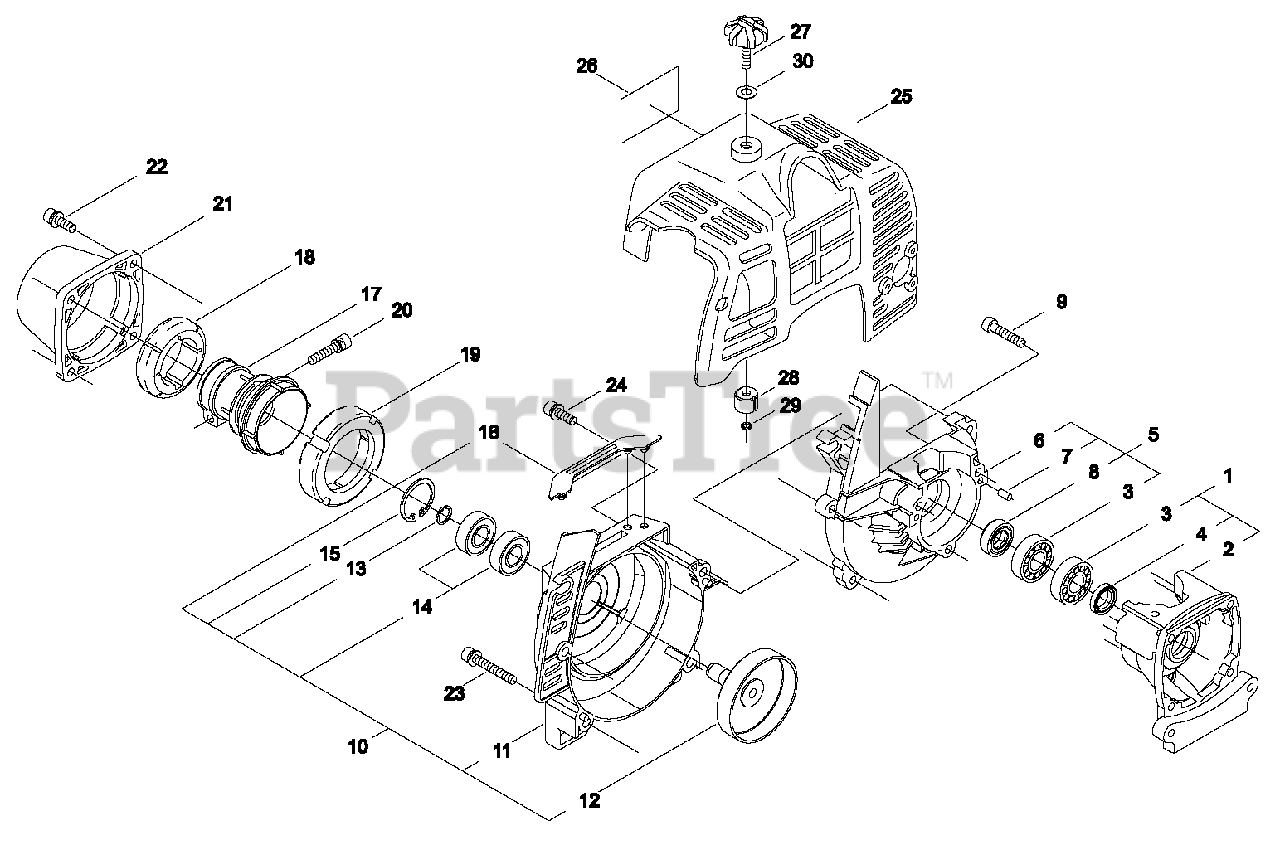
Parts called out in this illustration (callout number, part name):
1	CRANKCASE ASSY - REAR
2	CRANKCASE - REAR
3	BEARING, BALL - 6001
4	SEAL, OIL - 12
5	CRANKCASE ASSY - FRONT
6	CRANKCASE - FRONT
7	PIN - LOCATING
8	CRANKCASE ASSY - FRONT
9	SCREW - 5X25
10	FAN CASE ASSY
11	CASE, FAN
12	DRUM, CLUTCH
13	RING, RETAINING
14	BEARING, BALL - 6000ZZ
15	RING, RETAINING - 26
16	CUSHION
17	CLAMP, MAIN PIPE
18	CUSHION - FRONT
19	CUSHION - REAR
20	SCREW - 5X25
21	CAP
22	SCREW - 5X16
23	SCREW - 5X45
24	SCREW - 5X16
25	COVER, ENGINE
26	LABEL - IDENTIFICATION
27	THUMBSCREW
28	INSULATOR
29	CLIP
30	WASHER - CONICAL
